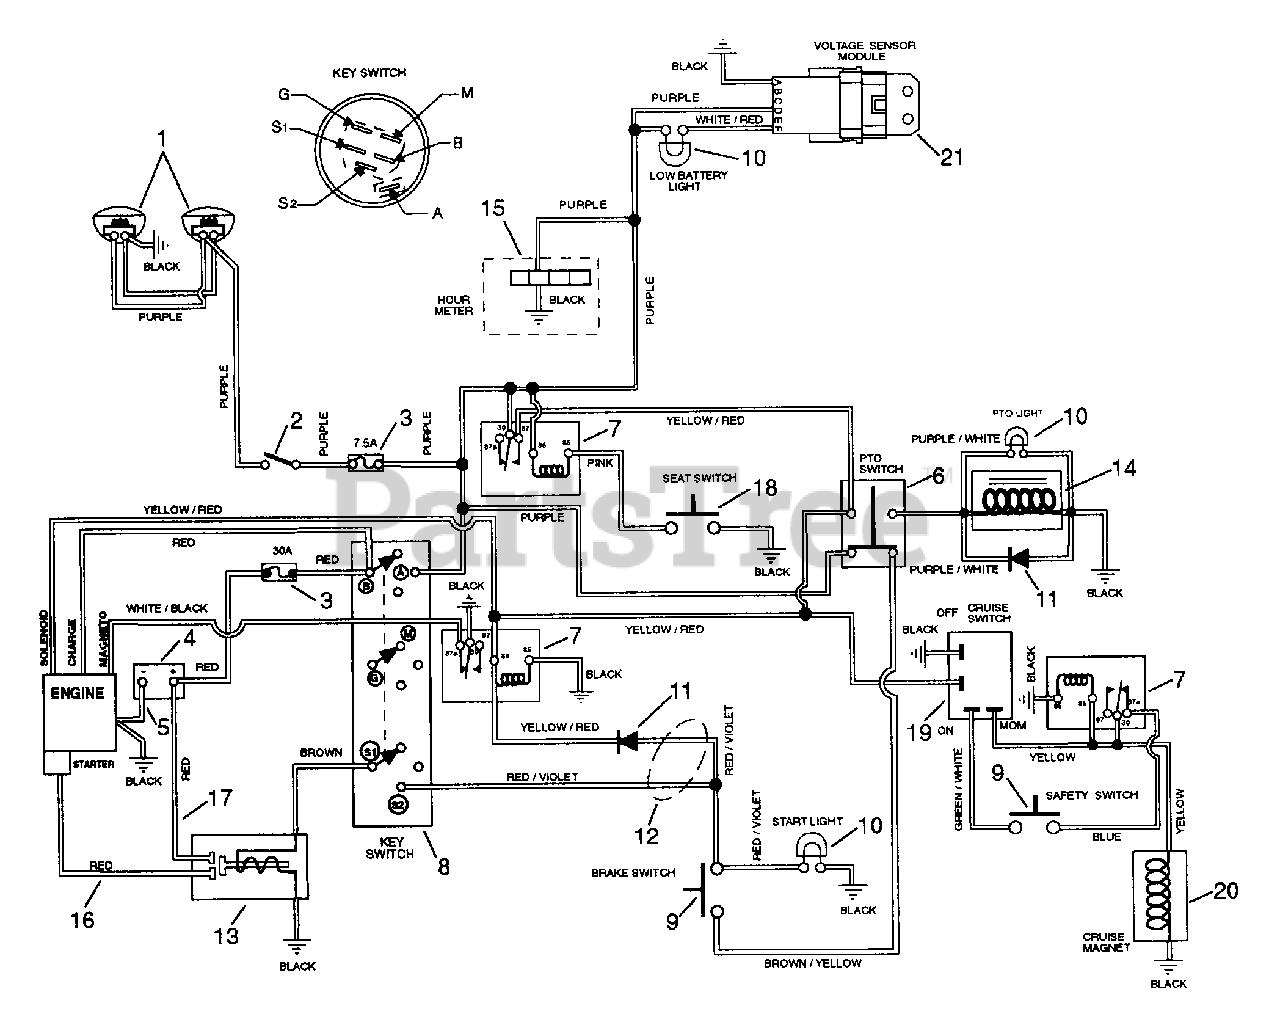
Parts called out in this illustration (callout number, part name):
1	HEADLIGHT- RH
1	HEADLIGHT- LH
2	SWITCH - LIGHT
3	7.5 AMP Fuse
3	30 AMP Fuse
4	BATTERY W/TUBE
5	GROUND CABLE .31X22.00X.31
6	PTO KNOB/ SWITCH ASSY
7	RELAY
8	KEY SWITCH
9	SWITCH- SINGLE POLE N.O.
10	#194 Bulb
11	MOLDED DIODE PLUG 1 AMP
12	WIRE HARNESS - 1640H B&S
13	SOLENOID
14	ELECTRIC CLUTCH/BRAKE (3.4AMP)
15	HOURMETER KIT- SIERRA
16	START CABLE 22"
17	STARTER CABLE 6.75"
18	SWITCH- SEAT
19	SWITCH - CRUISE
20	MAGNET
21	MODULE - VOLTAGE SENSOR
